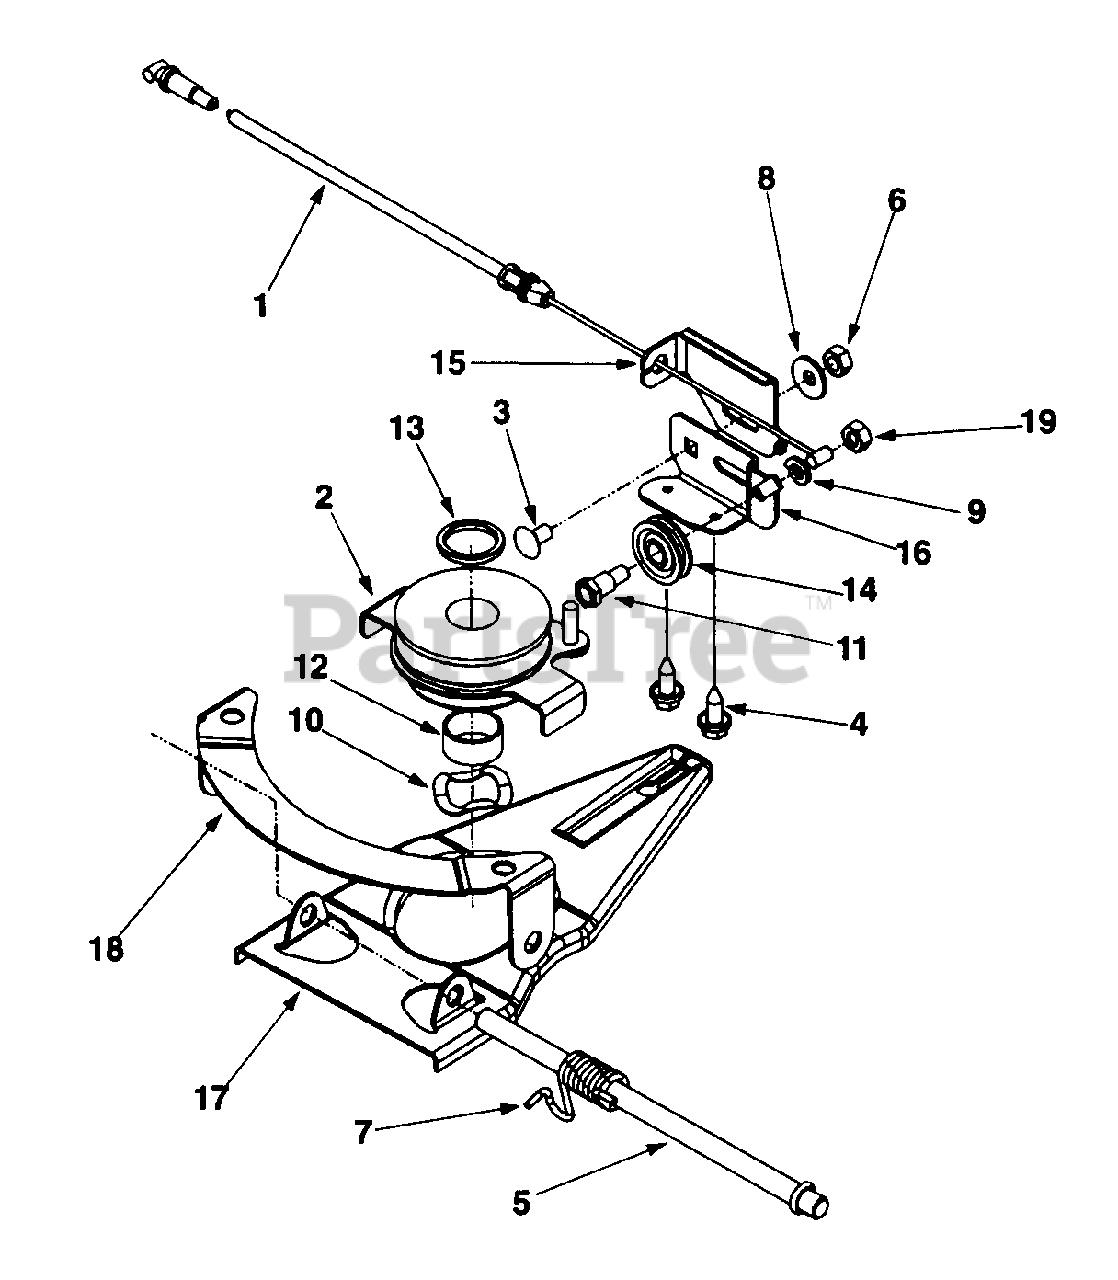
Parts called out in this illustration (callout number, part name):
1	6 Spd. Cable
2	Pulley Ass'y Multi- Spd.
3	Scr. 1/4-20 x .50 Carr.
4	Scr. AB 1/4-14 x .625 Hxinwsh
5	Pivot Shaft
6	Nut 1/4-20
7	Torsion Spring LH
8	Bell Wash. .265 X .75 X .062
9	Lock Wash. 1/4 Reg Duty
10	Wave Wash. 1.38 x .88 x .029
11	Shld. Scr. .375 x 1/4-14AB
12	Slev Spcr .88 ID x 1.00 OD x.48
13	Slev Spcr .88 ID x 1.13 ID x .12
14	Roller Cable
19	Hex Nut 1/4-28
